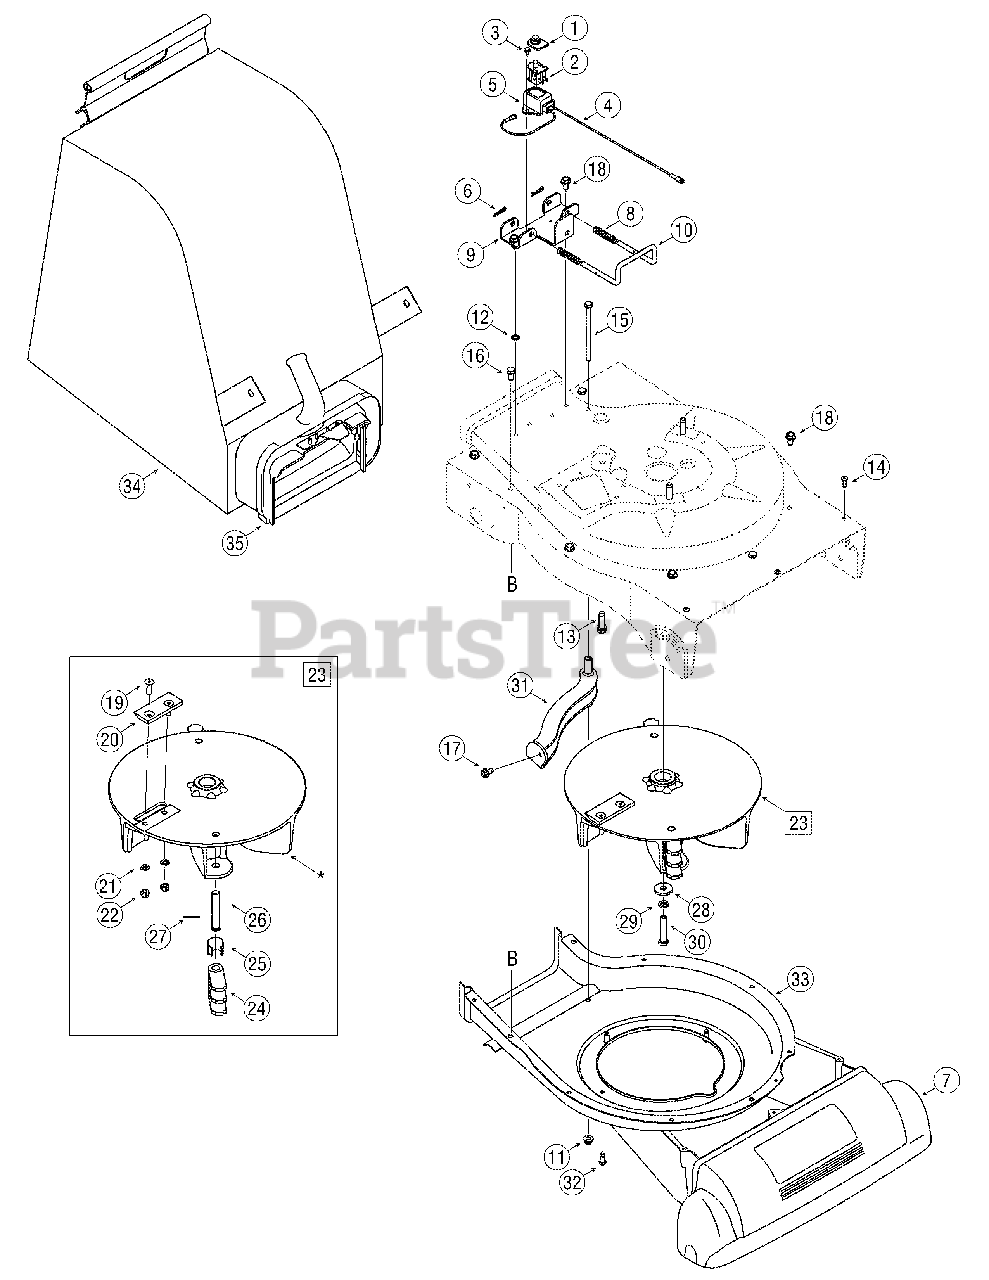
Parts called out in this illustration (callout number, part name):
1	Switch Cover
2	Safety Switch
3	Hex Washer Screw, #10-16 x.50
4	Wire Harness
5	Safety Switch Cover
6	Cotter Pin
7	Nozzle Cover
8	Compression Spring
10	Lock Rod
11	Flange Lock Nut, 5/16-18
12	External Lock Washer 5/16
13	Hex Washer Screw 3/8-16 x 1.25
14	Screw, #12-16 x .750
15	Hex Cap Screw 5/16-18 x 4.5
16	Hex Cap Screw 5/16-18 x.625
17	Screw, 5/16-18 x.500
18	Screw, 5/16-12 x.75
19	Hex Screw 5/16-24 x 1.0
20	Chipper Blade
21	Lock Washer 5/16
22	Hex Lock Nut 5/16-24
23	Impeller Assembly
24	Flail Blade
25	Pin Clip
26	Clevis Pin
27	Spiral Pin
28	Flat Washer.375 ID x 1.25 OD
29	Lock Washer 3/8
30	Hex Cap Screw 3/8-24 x 2.0
32	Shoulder Screw, .30 x .46
34	Bag Assembly
35	Chute Assembly
